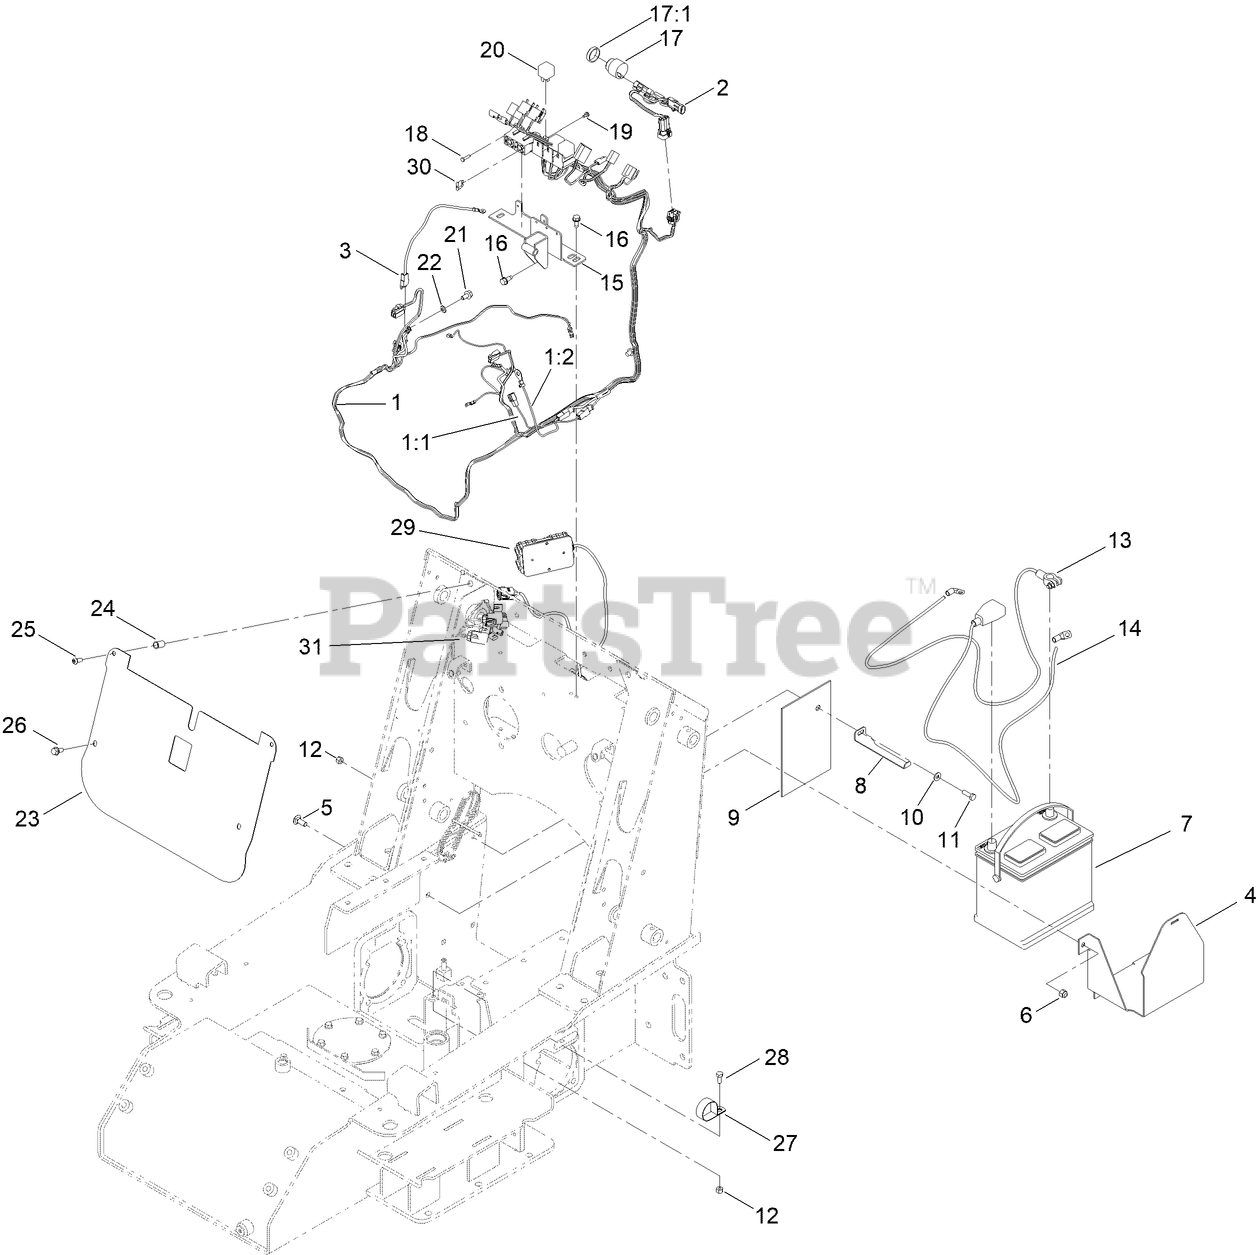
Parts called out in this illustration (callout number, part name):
1	HARNESS-WIRE
1:1	HARNESS-LINK, FUSIBLE
1:2	HARNESS-LINK, FUSIBLE (14FL)
2	HARNESS-WIRE, NEUTRAL
3	HARNESS-WIRE
4	MOUNT-BATTERY
5	BOLT-CARR
6	NUT-LOCK, NI
8	CLAMP-BATTERY
9	GUARD-BATTERY
10	WASHER-FLAT
11	SCREW-HH
12	NUT-LOCK, NI
13	CABLE-BATTERY, NEGATIVE
14	CABLE-BATTERY, POSITIVE
15	BRACKET-RELAY
16	SCREW-THD ROLL, HWH
17	AUDIO ALARM ASM
17:1	NUT-PLASTIC, KNURLED
18	SCREW
19	SCREW-HWH
20	RELAY
21	SCREW-HHF
22	WASHER-LOCK
23	BAFFLE-ELECTRICAL
24	NUT-CLINCH
25	SCREW-HSBH
26	SCREW-HHF
27	CLAMP-R
28	SCREW-HH
29	M7L-LITE ZTR KIT ASM
30	FUSE-BLADE, 10 AMP
31	HARNESS-WIRE, MACHINE ZTR
